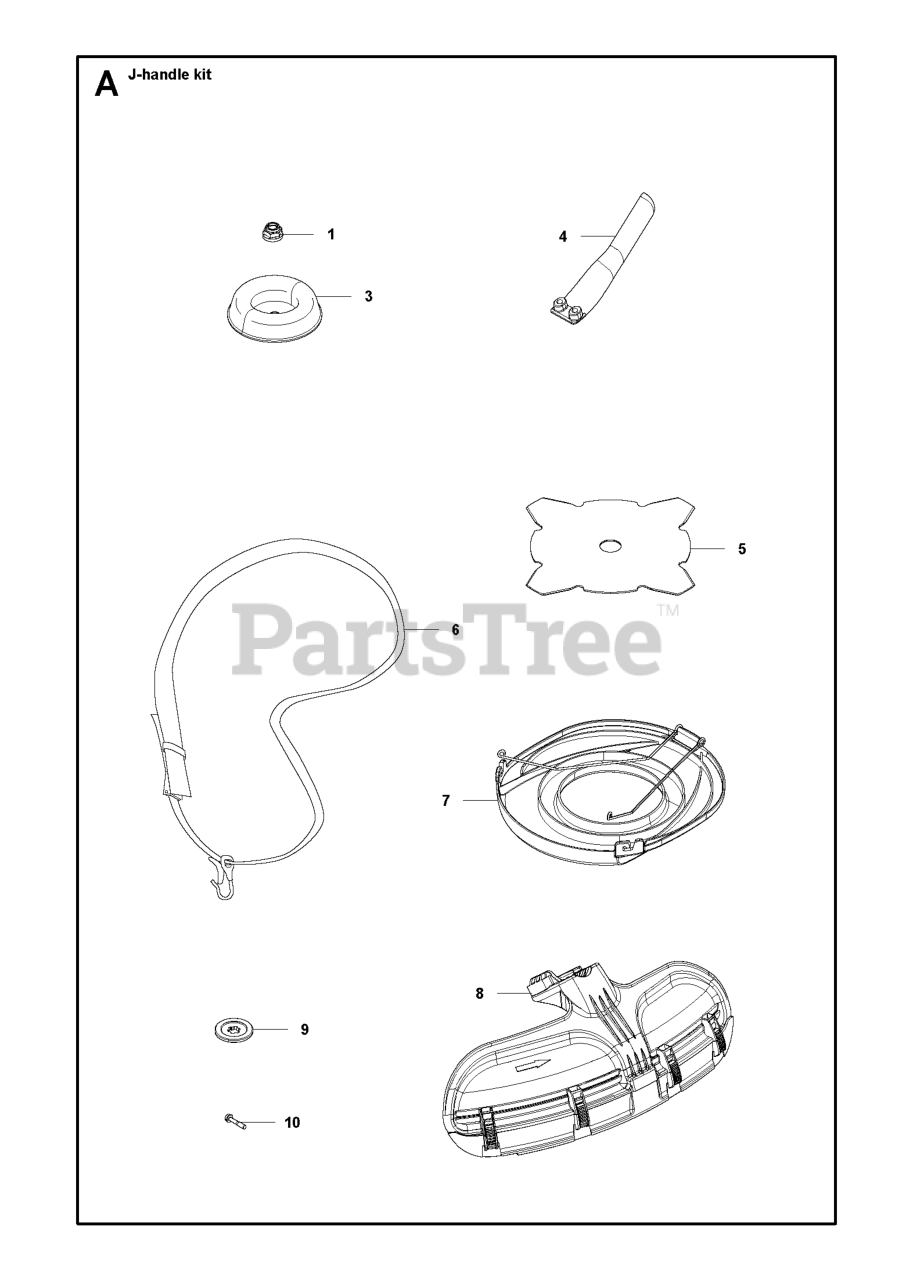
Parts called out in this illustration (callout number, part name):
3	SUPPORT CUP
5	Blade - Grass
6	Harness - Diagonal with sign
6	Harness-w/o warning
7	BLADE GUARD TRANSPORT
8	COMBI PROTECTOR
10	SCREW IHSCFTO
